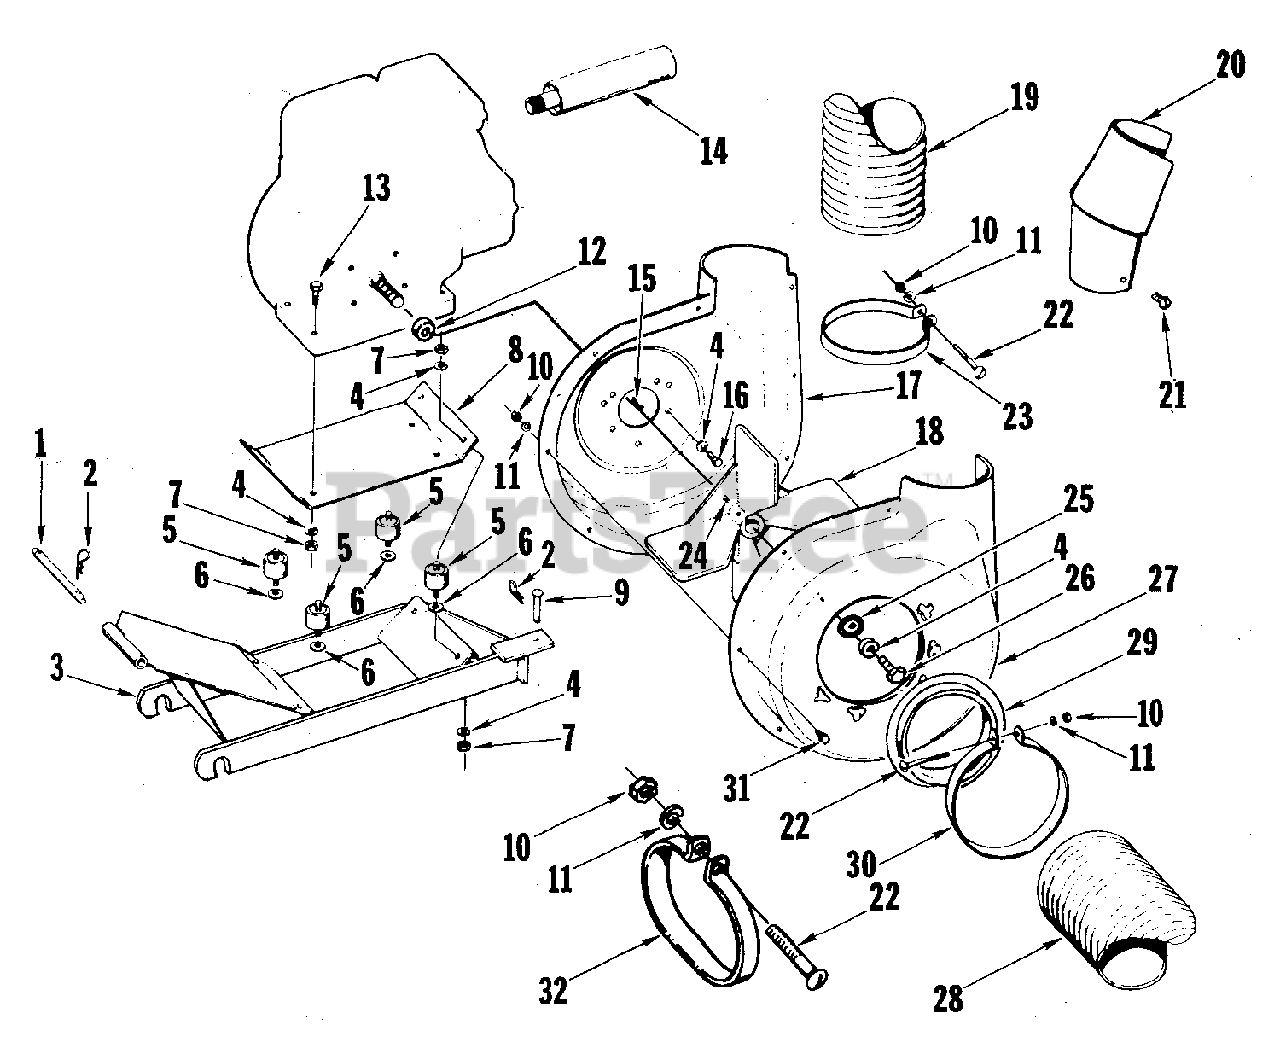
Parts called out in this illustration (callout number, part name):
3	FRAME ASSEMBLY
4	WASHER, Lock, 5/16"
5	CONNECTOR, Cushion
6	WASHER, Flat, 5/16
7	NUT, Hex, 5/16-18
8	PLATE, Engine
10	NUT, Hex, 1/4-20
11	WASHER, Lock, 1/4
13	SCREW, Cap, 5/16-18 x 1-1/2
16	SCREW, Cap, 5/16-24 x 5/8
17	HOUSING, Blower (R.H.)
18	FAN ASSEMBLY
19	HOSE, Exhaust
21	SCREW, Self Tapping, #10 x 3/8
22	SCREW, Round Head, 1/4-20 x 3
24	SCREW, Set, 5/16-18 x 1/2
26	SCREW, Cap, 5/16-24 x 3/4
27	HOUSING, Inlet, Half
28	HOSE, Intake
29	FLANGE, Hose
31	SCREW, Cap, 1/4-20 x 1/2
